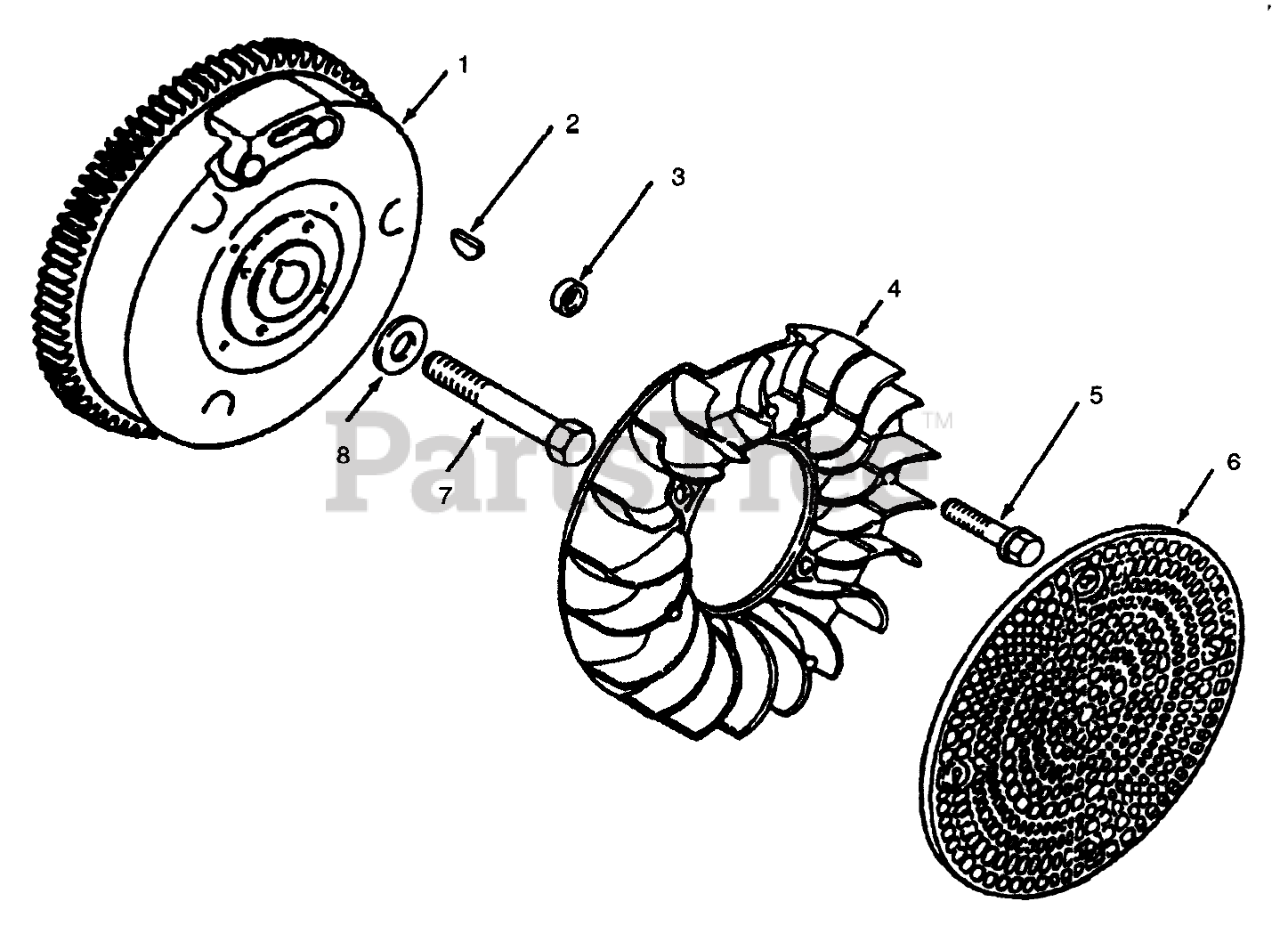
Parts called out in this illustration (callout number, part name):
1	Flywheel
2	Key-Woodruff
3	Spacer
5	Screw-Hex. Hd.
6	Screen
7	Screw
8	Washer
